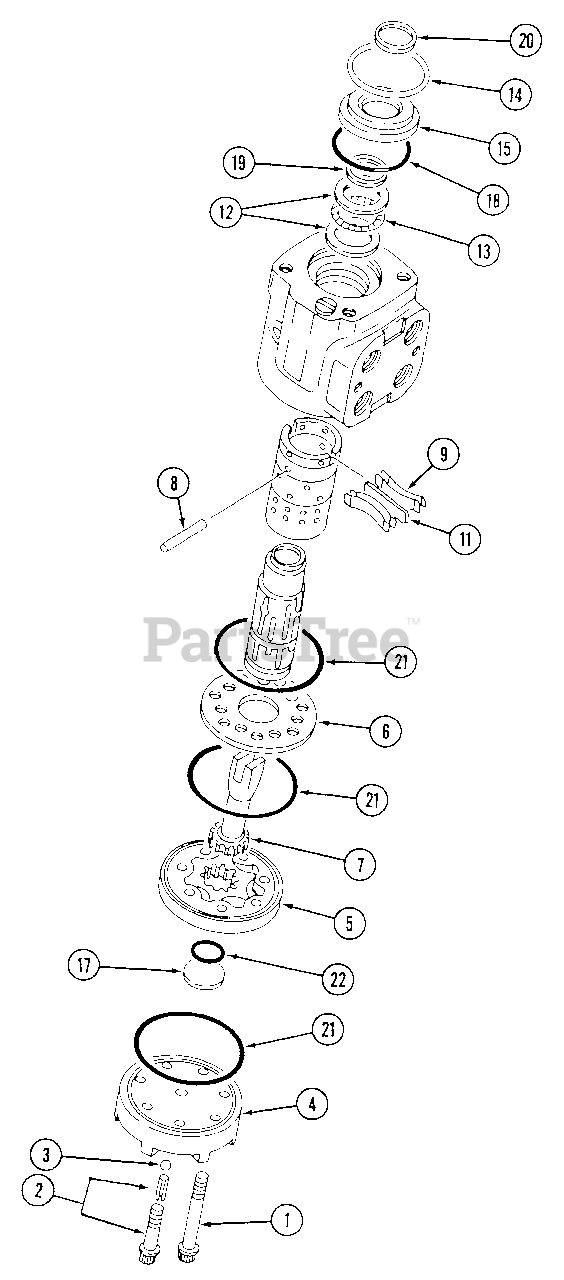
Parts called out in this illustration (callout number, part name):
2	Retainer, Screw Ass'y.
6	Plate, Spacer
9	Spring, Centering
13	Bearing, Needle
18	O-Ring
19	Oil, Seal
20	Seal, Dust
